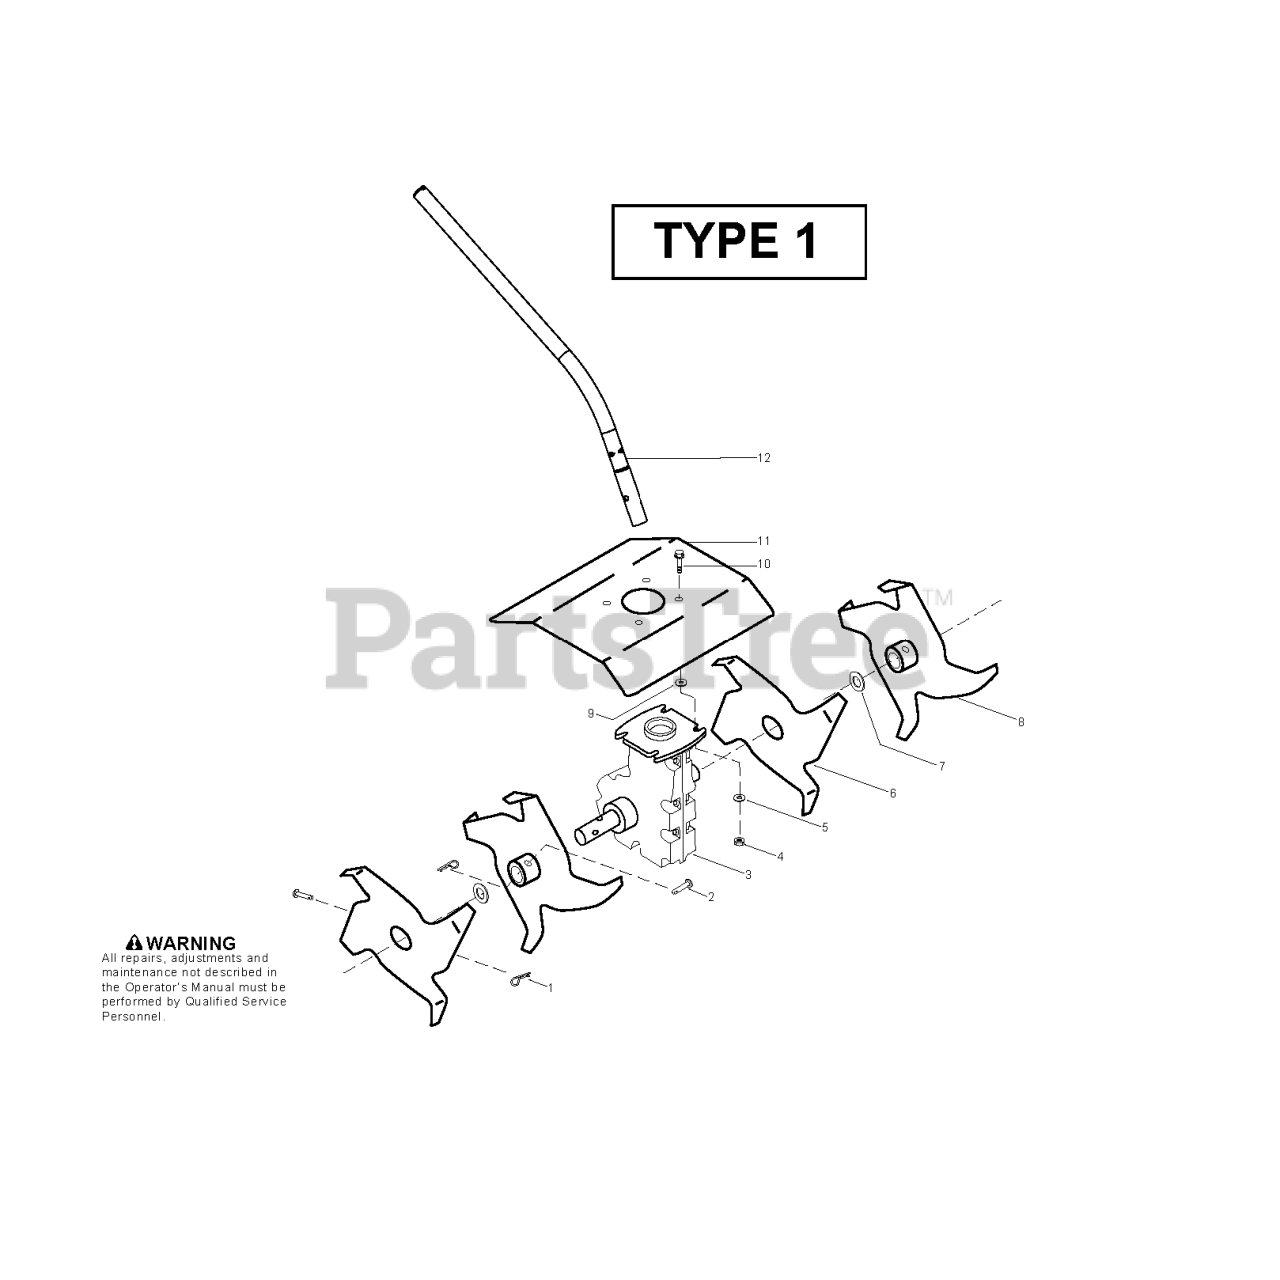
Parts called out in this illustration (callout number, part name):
1	RETAINER,HAIRPIN
2	PIN,CLEVIS
3	GEAR ASSY GEARBOX
5	WASHER,FLAT
6	TINE,RIGHT OUTSIDE/LEFT INSIDE
7	WASHER,FELT
8	TINE,LEFT OUTSIDE/RIGHT INSIDE
9	WASHER,FLAT
10	BOLT,WASHER HEAD
